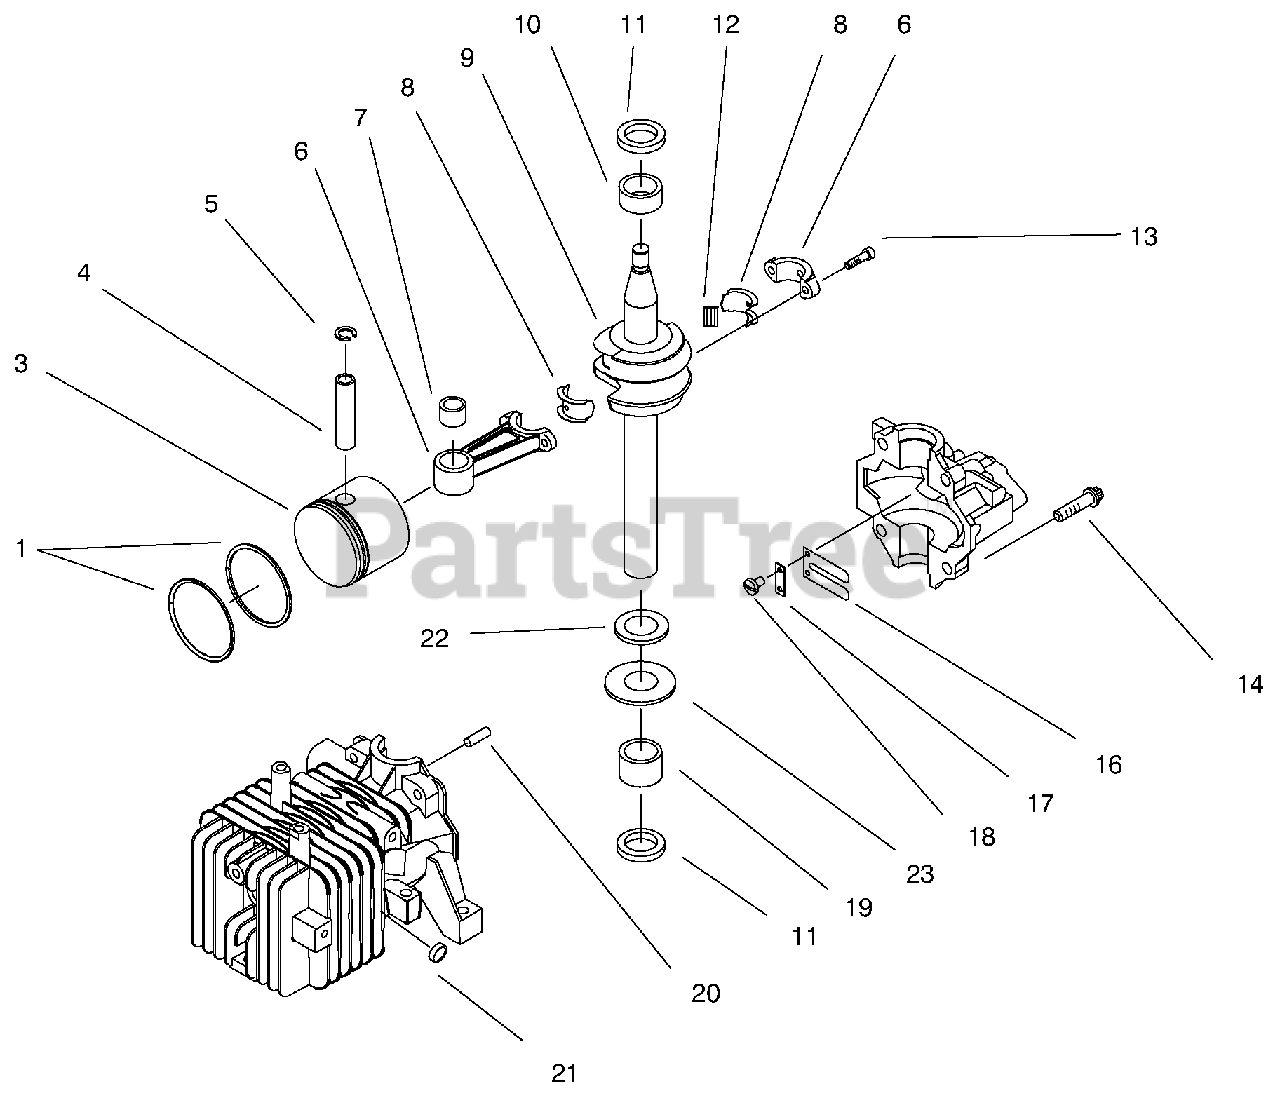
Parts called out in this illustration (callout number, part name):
1	F-RING SET
3	Piston & Connecting Rod (Incl. Ref. #1, 3-7 & 13)
4	PIN-WRIST VF
5	RING-RETAINING
6	Connecting Rod Assembly (Incl. Ref. #8, 12 & 13)
7	BEARING XEV
8	LINER ASM
9	C/SHAFT 48CM FV
10	BEARING V
11	SEAL-OIL
12	Roller Strip
13	SCREW-HSH
14	SCREW-HWH V
16	REED-CARBURETOR
17	PLATE-BACKUP, REED
18	SCREW-HH
19	BEARING V
20	DOWEL XEV
21	PLUG-CORE VF
22	BEARING-THRUST
23	WASHER-THRUST
